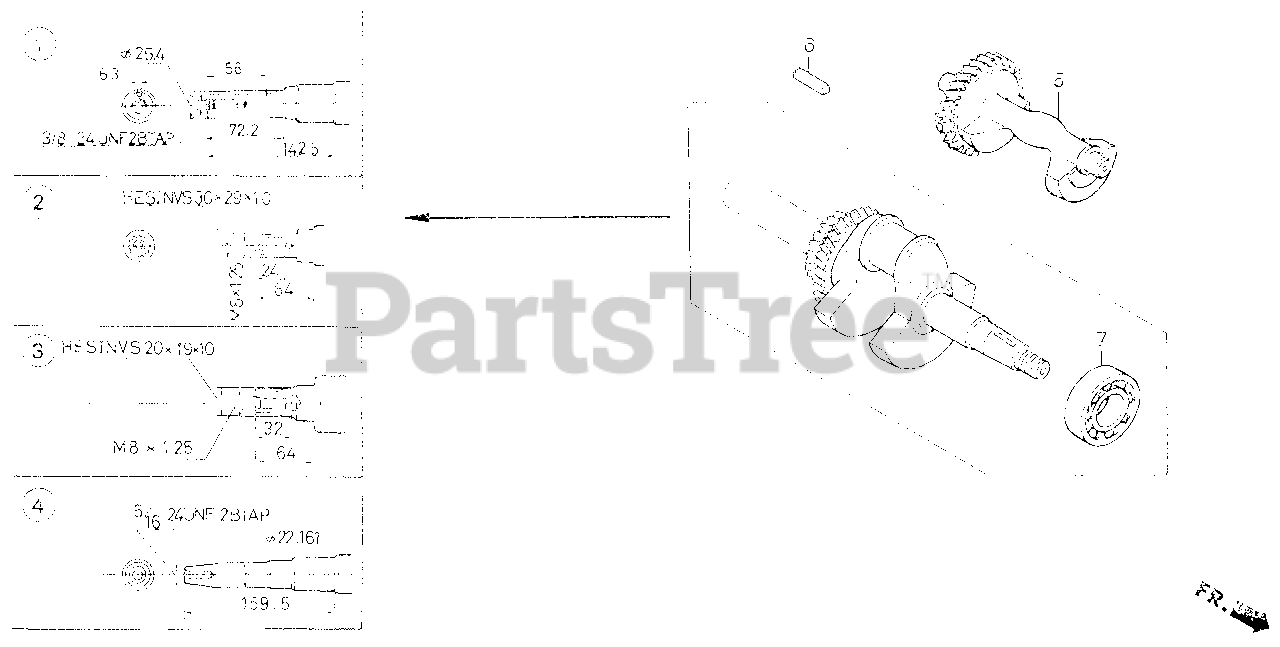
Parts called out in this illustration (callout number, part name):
1	CRANKSHAFT (Q-TYPE)
5	WEIGHT, BALANCER
6	KEY (6.3X6.3X43)
7	BEARING, RADIAL BALL (6207)
